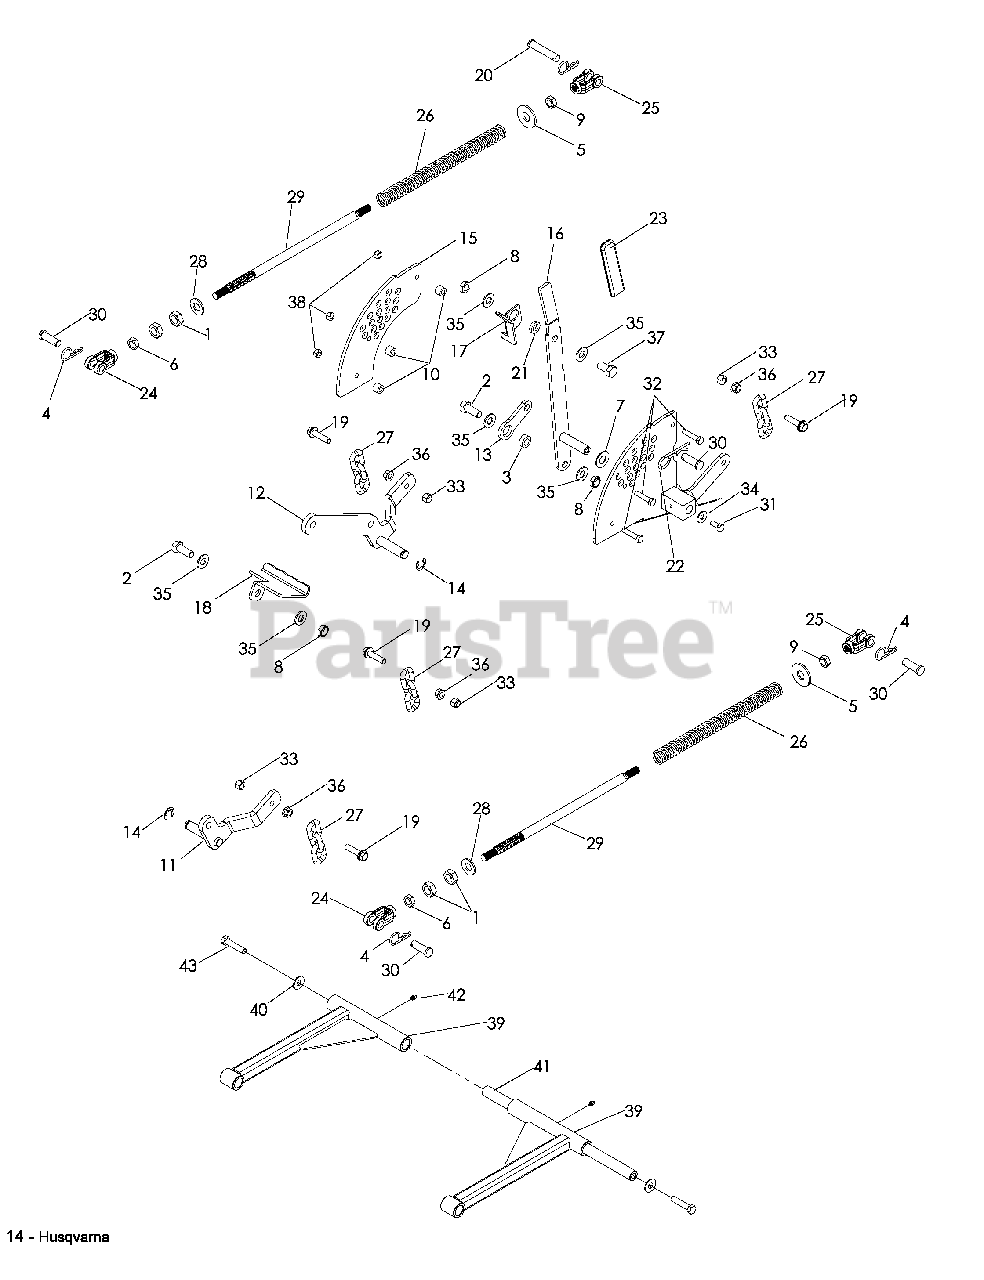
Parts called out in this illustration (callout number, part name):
1	NUT 5/8-11 JAM
2	HHB ½-13 x 1¼
3	BLADE ADAPTOR
4	HAIR PIN COTTER
5	WASHER 5/8
6	NUT ½-20 JAM
7	WASHER 5/8 x .063
8	NUT ½-13 NYLOC
9	NUT ½-20 JAM LH
11	LIFT ARM LH
12	LIFT ARM RH
13	LINK, LIFT HANDLE
14	E-RING 7/8
15	OUTER QUADRANT
16	LIFT HANDLE
17	LIFT LATCH
18	FOOT PEDAL
19	HHB 3/8-16 x 1½ FLG
20	CLEVIS PIN
22	HAIR PIN COTTER
23	GRIP, BRAKE HANDLE
24	CLEVIS RH FEMALE
25	CLEVIS LH FEMALE
26	LIFT SPRING
28	WASHER, .65 x 1¼
30	CLEVIS PIN ½ x 1½
31	HHB 5/16-18 x ¾
32	HHB 5/16-18 x 1½
33	NUT 3/8-16 NYLOC
34	WASHER 5/16
35	WASHER ½ NARROW
36	NUT 3/8-16 FLANGE
37	HHB ½-13 x 1
38	NUT 5/16-18 NYLOC
39	ARM, TRAILING
40	WASHER, 3/8
41	SPACER, FRAME
42	ZERK, GREASE ¼
43	SCREW, MACHINE
